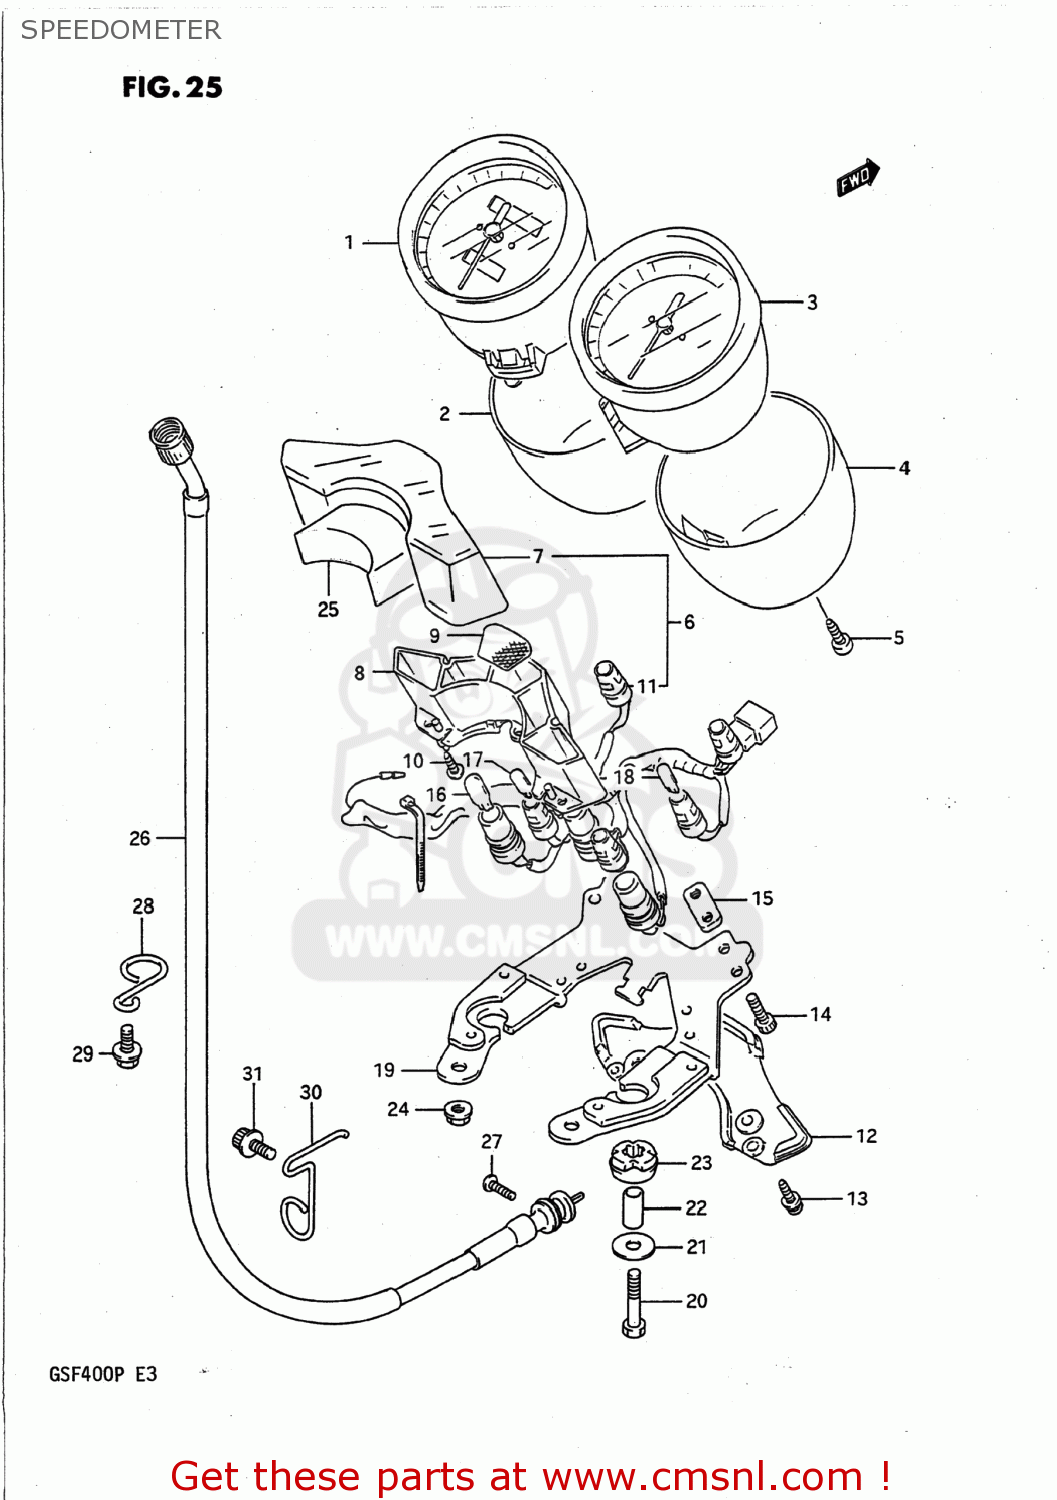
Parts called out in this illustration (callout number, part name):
1	SPEEDOMETER(KILO)
2	LWR CASE,SPEEDOMETER
3	TACHOMETER
4	LOWER CASE,TACHOMETER
5	SCREW
6	BOX PILOT
7	UPR CASE
8	INNER CASE
9	LENS SET,PILOT
10	SCREW
11	SOCKET
12	LOWER CASE
13	SCREW
14	BOLT
15	PLATE
16	BULB(12V3.4W,T10,BF175-01450A)
17	BULB(12V3W,WB371,T7)
18	BULB(12V1.7W,WB372,T7)
19	BRACKET,METER
20	BOLT
21	WASHER
22	SPACER
23	CUSHION
24	NUT
25	CUSHION,PILOT LAMP
26	CABLE ASSY,SPEEDOMETER
27	SCREW
28	CLAMP,SPEEDOMETER CABLE
29	BOLT
30	CLAMP,SPEEDOMETER CABLE
31	BOLT
